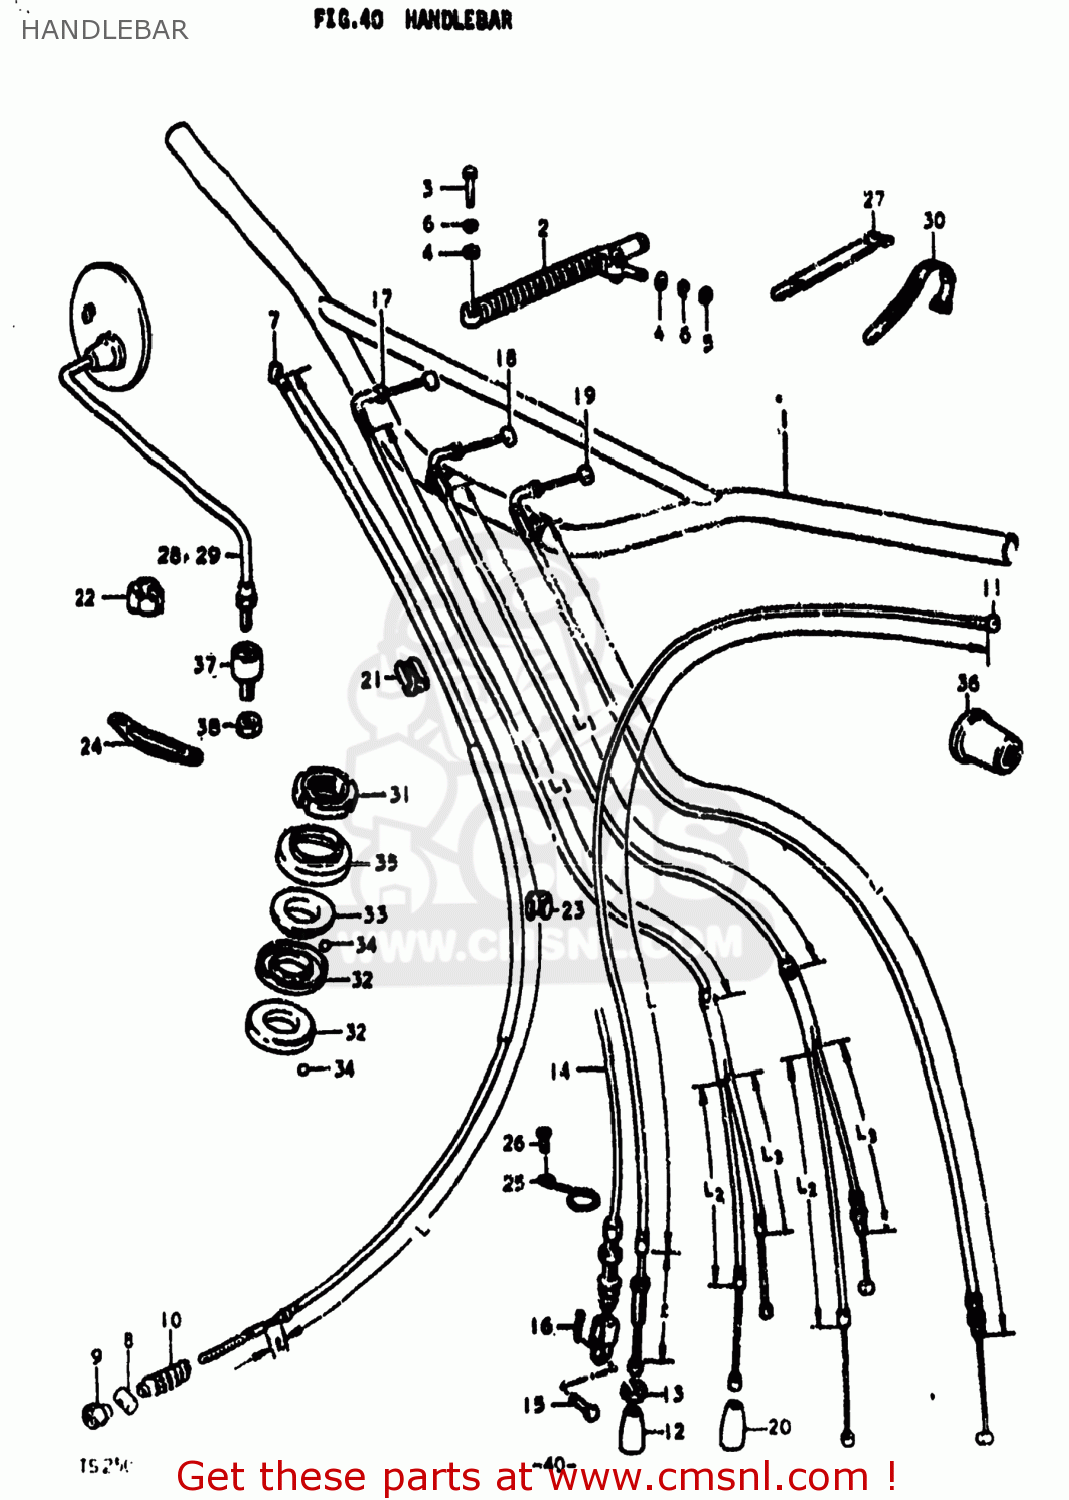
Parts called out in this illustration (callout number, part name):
1	HANDLEBAR
2	DAMPER ASSEMBLY,HANDLE
3	BOLT
4	WASHER
5	NUT
6	LOCK WASHER
7	CABLE,FR BRAKE
8	PIN
9	NUT
10	SEAL,DUST
11	WIRE,CLUTCH
12	OIL SEAL
13	NUT
14	WIRE,CLUTCH
15	PIN(L:15)
16	PIN
17	CABLE ASSEMBLY,THROTTLE
18	CABLE ASSEMBLY,THROTTLE
19	CABLE ASSEMBLY,THROTTLE
20	SEAL,DUST(7X18X30)
21	CLIP
22	CLAMP
23	CLIP
24	GUIDE,CABLE
25	CLIP
26	SCREW
27	CLAMP
28	MIRROR ASSEMBLY,RIGHT
29	MIRROR ASSEMBLY,LEFT
30	CLAMP(L:120)
31	NUT,STEERING STEM(25X44X10)
32	LACE,STEERING INNER LWR
33	LACE,STEERING OUTER UPR
34	BALL
35	DUST SEAL,STEERING UPR
36	COVER,FRONT TURN SIGNAL BRACKET
37	RUBBER
38	NUT
